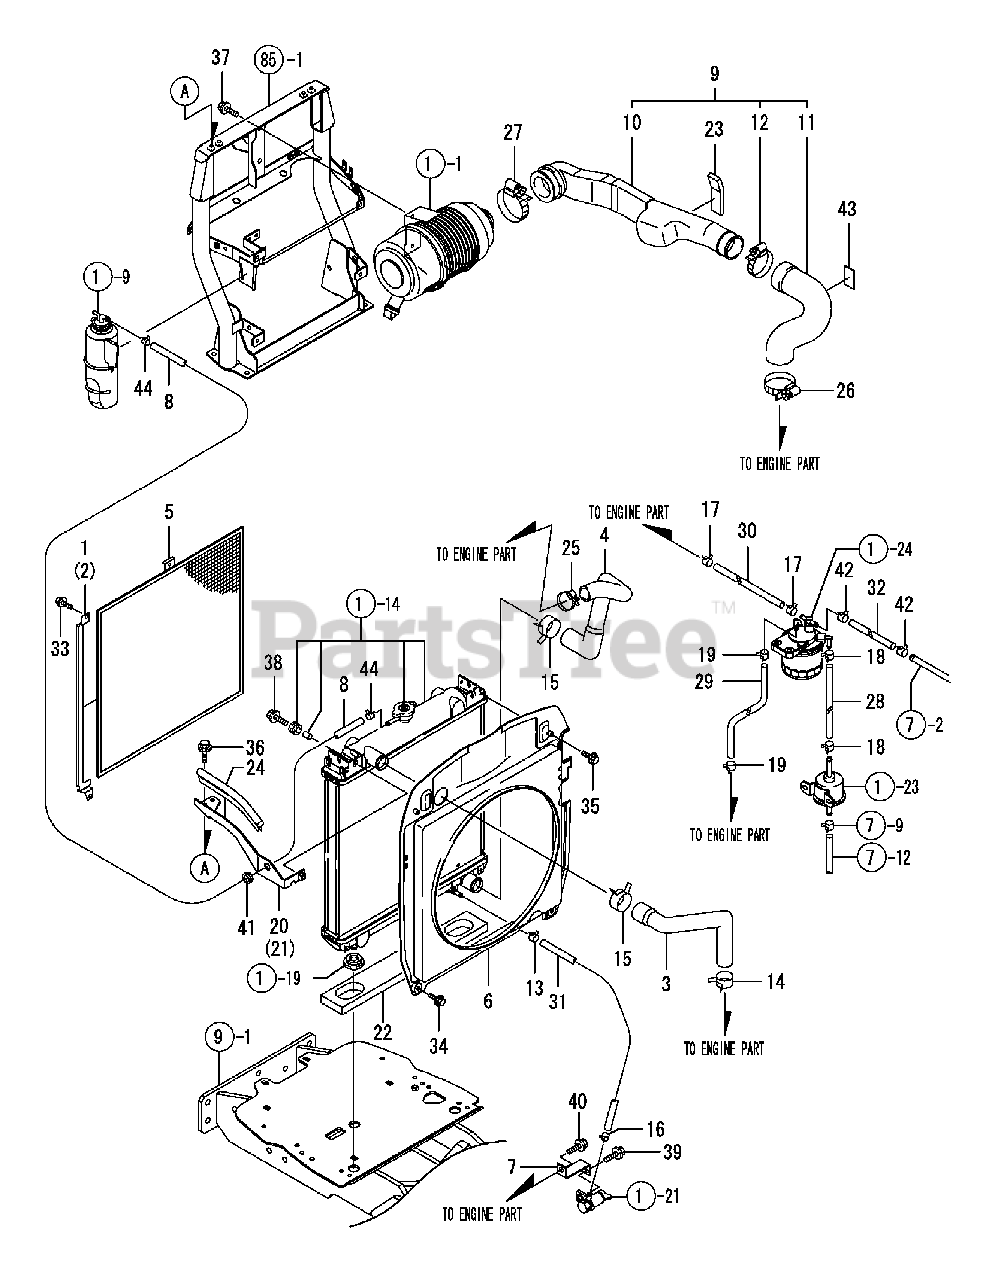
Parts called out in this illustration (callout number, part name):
1	RAIL, RADIATOR L
2	RAIL, RADIATOR R
3	PIPE, COOLING WATER
4	PIPE, COOLING WATER
5	SCREEN,RADIATOR
6	SHROUD M ASSY, FAN
8	PIPE,OVERFLOW(500
9	PIPE ASSY, INTAKE
10	PIPE SUB-ASSY, A
11	HOSE, INTAKE B
20	STAY ASSY, L.H.
21	STAY ASSY, R.H.
22	URETHANE, RADIATOR
23	URETHANE, HOSE
24	STRIP 250,WEATHER
27	CLAMP 80
28	HOSE, 7.3 X 180
29	FUEL PIPE 7.3X350
30	FUEL PIPE 7.3X400
31	FUEL PIPE 7.3X400
32	HOSE 7.3X680,BRAIDED
33	BOLT M 6X 12 PLATED
34	BOLT M 6X 12 PLATED
35	BOLT M 6X 25 PLATED
36	BOLT M 8X 16 PLATED
37	BOLT M 8X 16 PLATED
38	BOLT M 8X 25 PLATED
39	BOLT M 8X 16 PLATED
40	BOLT M10X 16 PLATED
41	GROMMET 13
